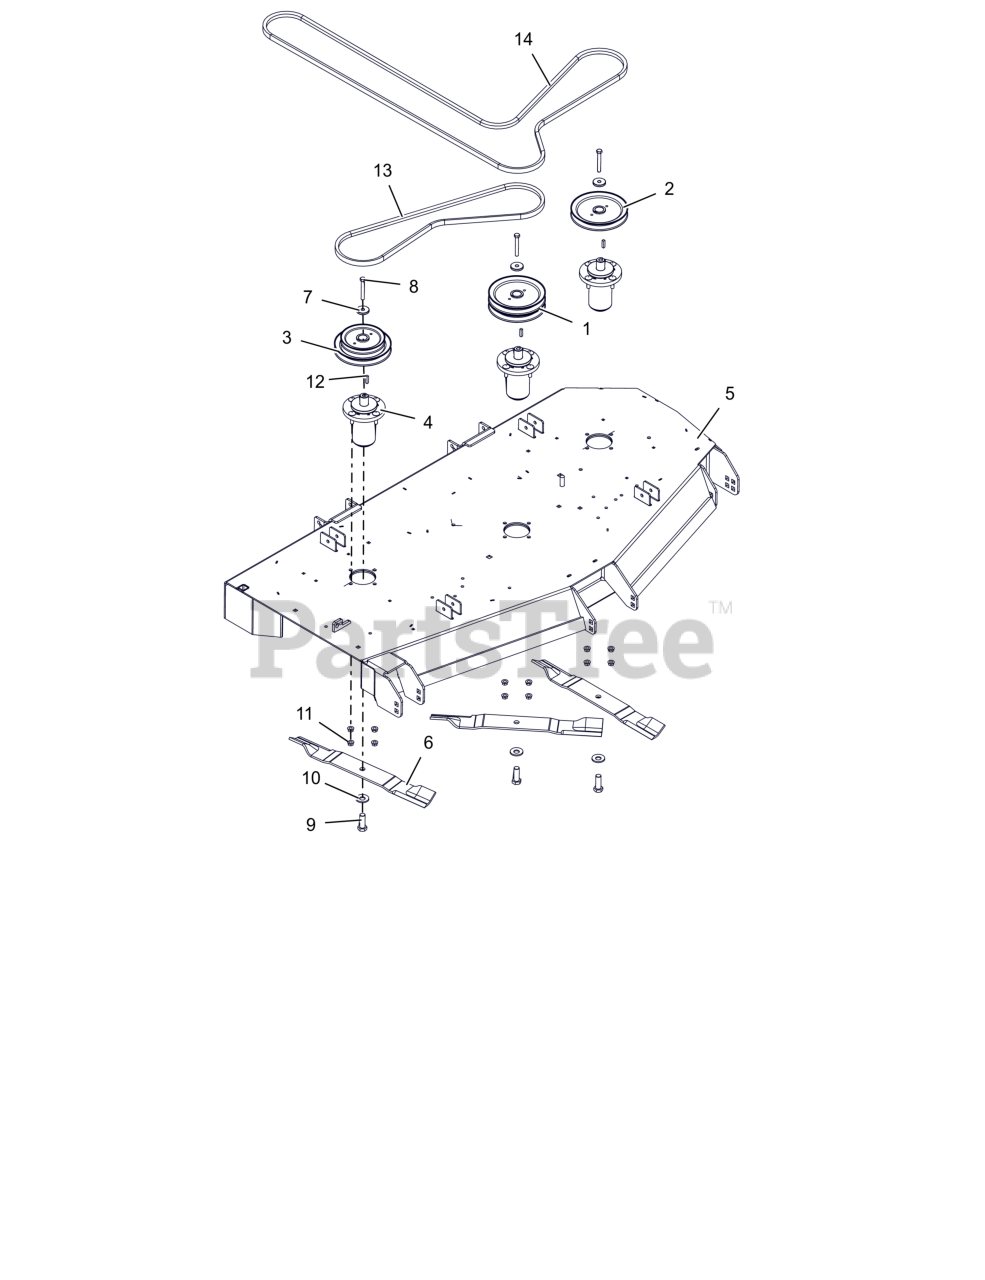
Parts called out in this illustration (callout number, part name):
1	PULLEY, DOUBLE 1.000 ID X 6.750 OD
2	PULLEY, V-1" ID X 6.75 OD
3	PULLEY, DBL-1"IDX6.75"&5.25"OD
4	ASM, MAINT FREE ALUM SPINDLE
5	WLDMT, 60" SIDE DISCH DECK (RED) W/ SAFETY DECALS
6	BLADE, MOWER (20.50")
7	RETAINER, SHEAVE
8	BLT, HEX .38-16X2.75 G8 ZCC
9	BLT, HEX .62-18X1.75 G8 ZCC
10	WSHR-BLVL .669X1.535X.138
11	NUT-LK-CTR-FLG .375-16 GF ZCC
12	KEY, SQ .25X.25X1.00 RC 40-50
13	V-BELT, B-COGGED
14	BELT, B-SECTION EPDM RAW EDGE
